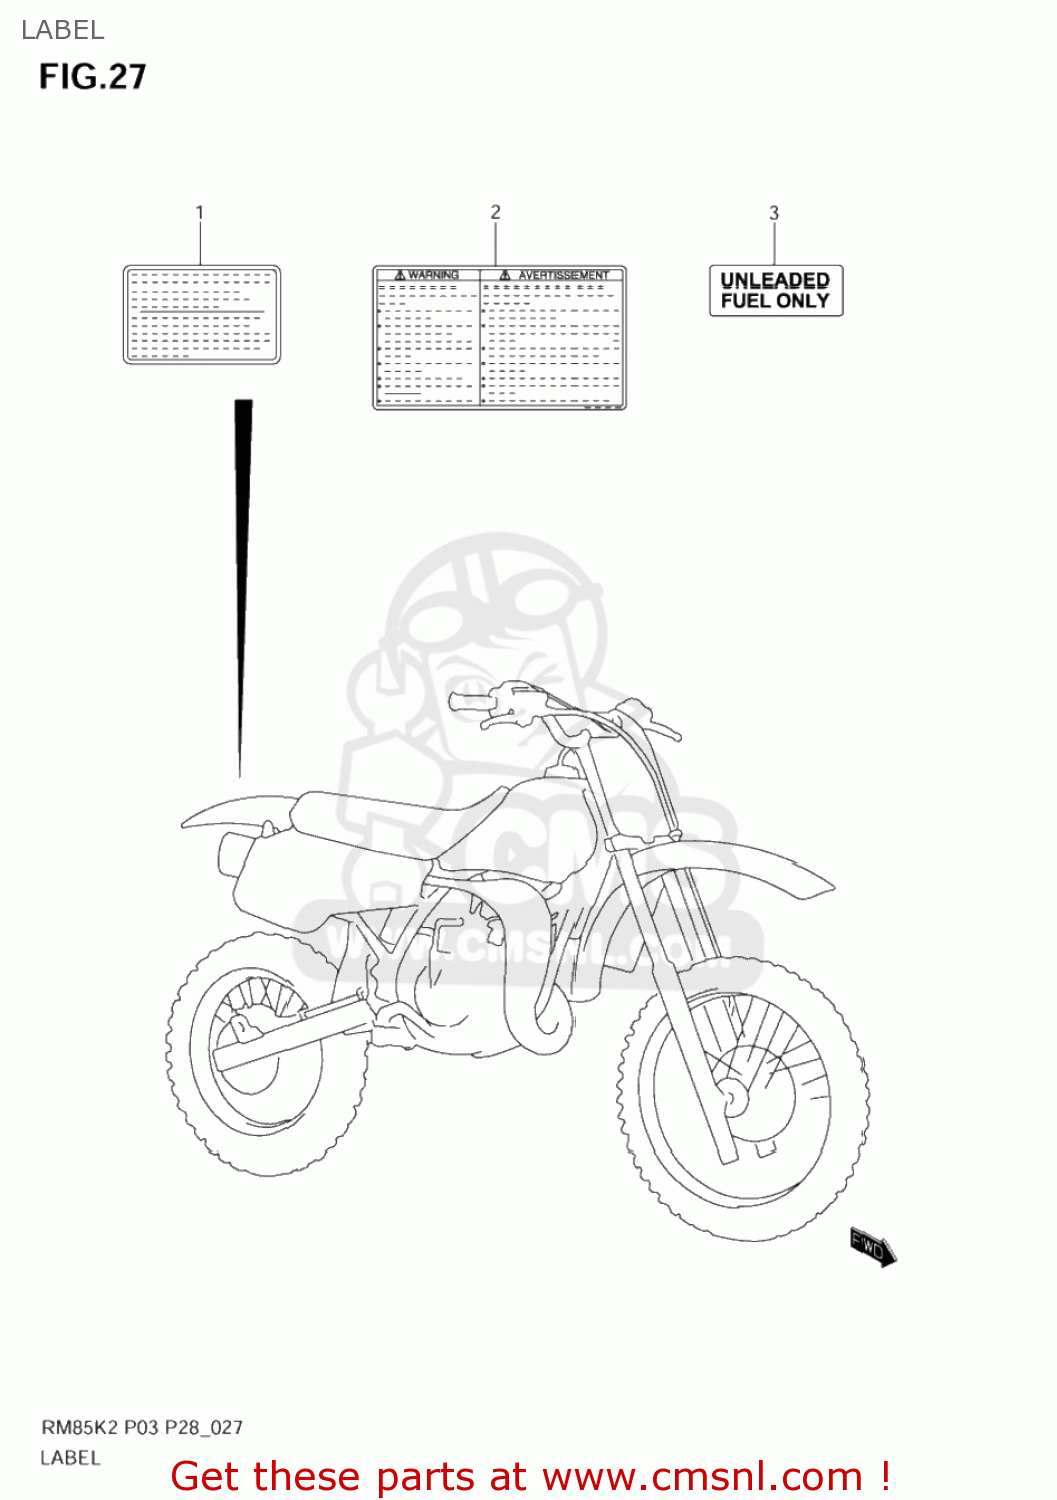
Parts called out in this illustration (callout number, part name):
1	LABEL,WARNING NO.2
2	LABEL,WARNING
3	LABEL,UNLEADED FUEL
4	MANUAL,OWNER'S
